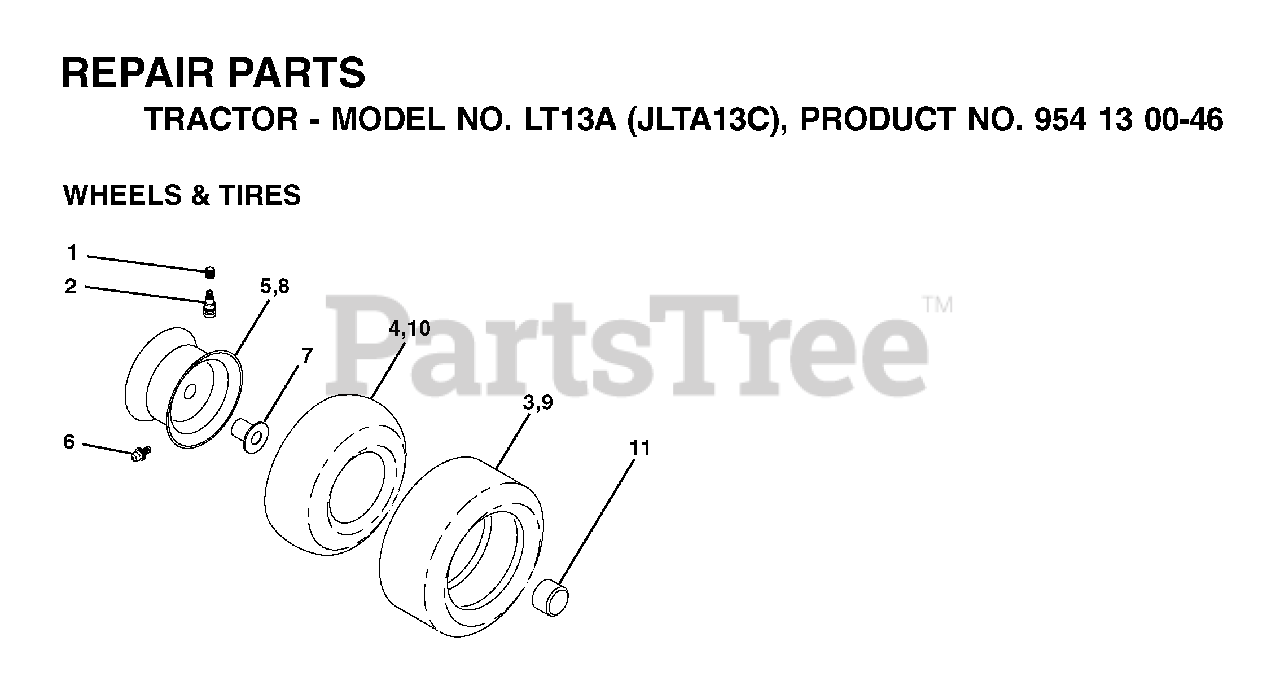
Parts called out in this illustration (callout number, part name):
1	VALVE CAP
2	VALVE STEM LT
3	TIRE HEAVY DUTY
4	TUBE.5.3/4.5/6
5	RIM ASM 6" FRONT SILVER
6	FITTING LT
7	BEARING T
8	RIM ASM 8" REAR SILVER
9	TIRE
10	TUBE
11	CAP, AXLE BLK
